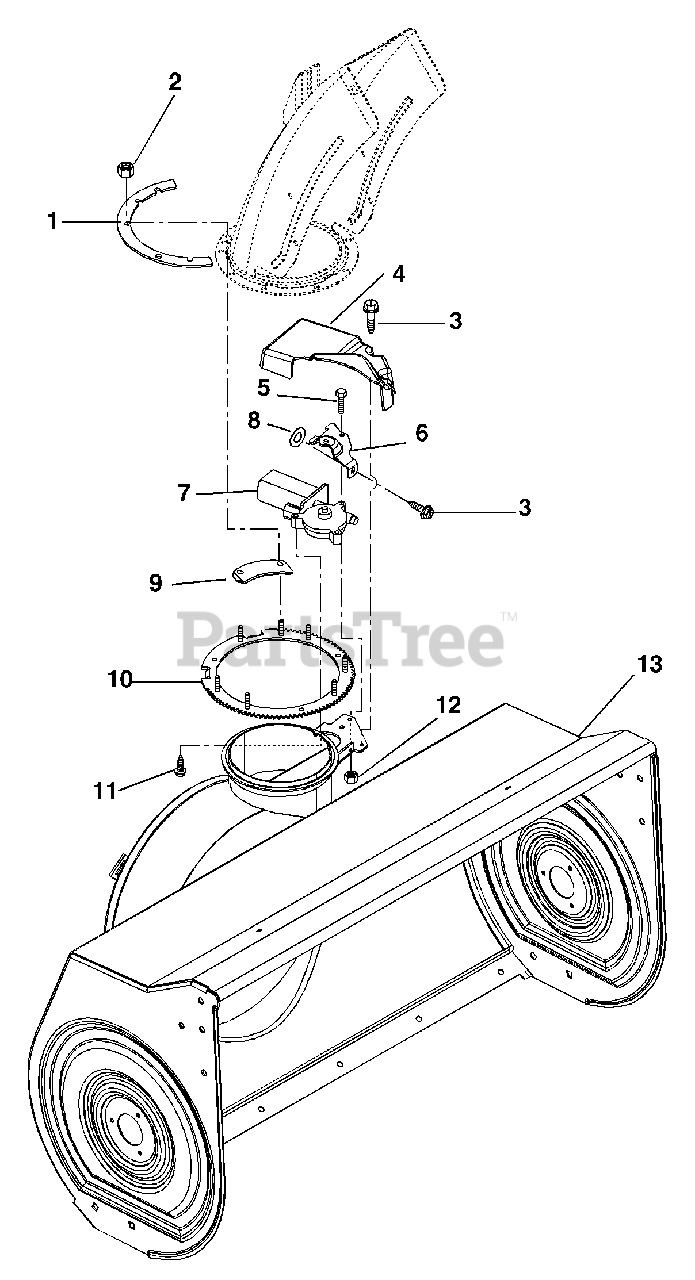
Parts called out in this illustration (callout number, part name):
1	RING, COVER
2	@NUT-SPNLK-FLG .25-20 YWZC
3	@SCR-TAP 12-24X.50 HWH TR YWZC
4	COVER, MOTOR
5	@BLT-HEX .25-20X1.25 GR5 YWZC
6	BRACKET, ELECTRIC MOTOR
7	MOTOR, ELECTRIC RH - CHUTE
8	@WSHR-FL-STL.281X.62X.065 YWZC
9	CLAMP, CHUTE
10	GEAR, CHUTE
11	@SCR-TAP .31-18X.75 HWH TR YWZ
12	@NUT-LK-CTR .25-20 YWZC
13	HOUSING, BLOWER-32"E
